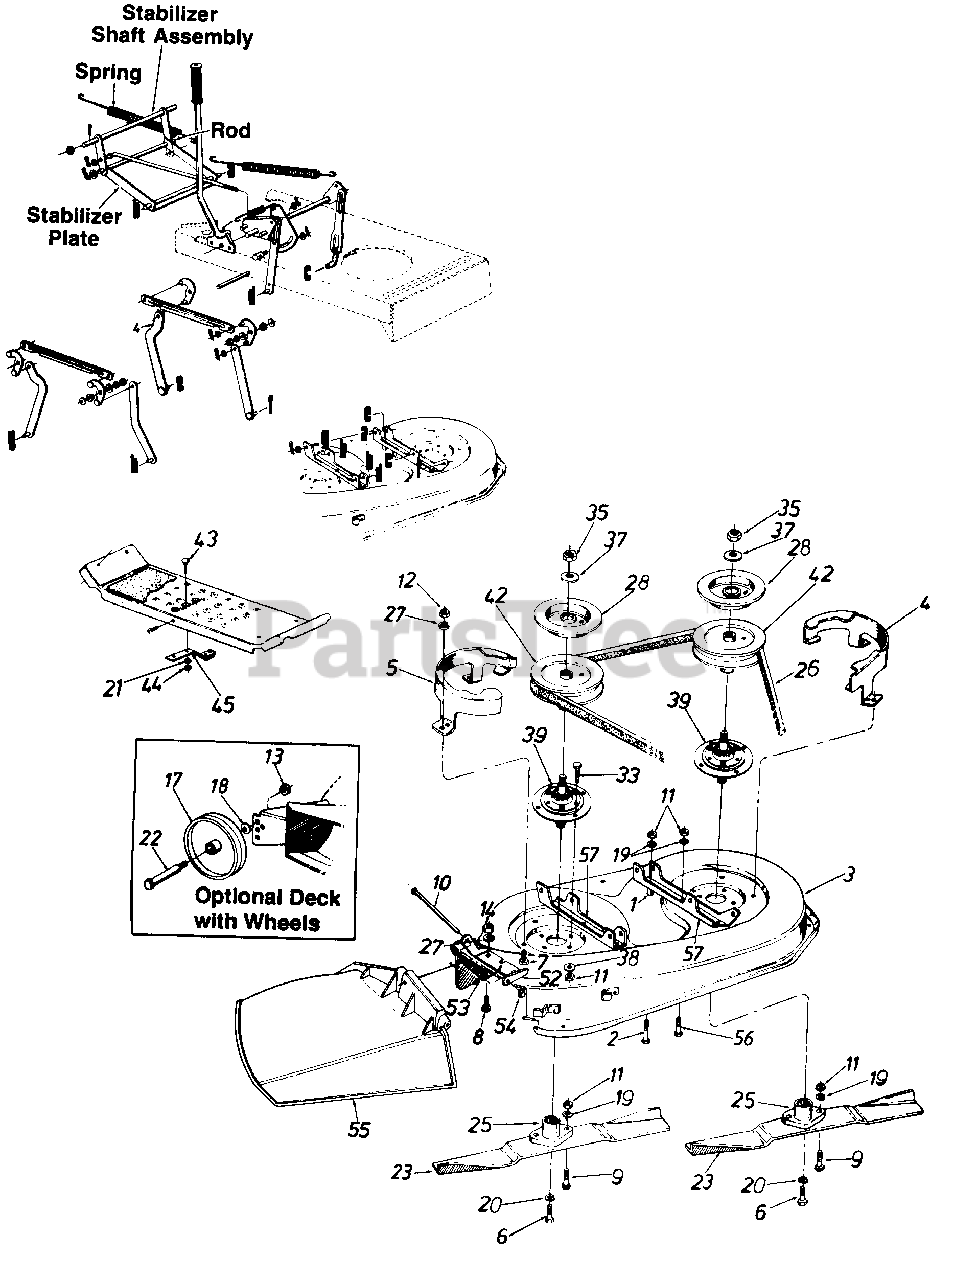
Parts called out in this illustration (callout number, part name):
1	Spacer.33" I.D. x .88"
2	Hex Bolt 5/16-24 x 1.25" Lg.
3	38" Deck Ass'y. w/Deck Wheels
7	Hex Bolt 1/4-28 x .62" Lg.
8	Truss Mach. Scr. 1/4-20 x .75"
9	Hex Bolt Special 5/16-24 x 1.0"
10	Hinge Pin
11	Hex Nut 5/16-24 Thd.
12	Hex Nut 1/4-28 Thd.
13	Hex Top L-Nut 3/8-16 Thd.
14	Hex Nut 1/4-20 Thd.
17	Deck Wheel 5"
18	Bell-Wash. 40" I.D. x .88" O.D.
19	L-Wash. 5/16" I.D.
20	L-Wash. 3/8" I.D. H.D.
21	L-Wash. l/4" I.D.
22	Shld. Bolt .498" Dia. x 1.53"
23	High-Lift Blade
25	Blade Adapter
26	V-Belt
27	Bell-Wash. 1/4" I.D.
28	Brake Disc
33	Hex Bolt 5/16-24 x .75* Lg.
35	Hex Jam Nut 5/8-18 Thd.
37	L-Wash. 5/8" I.D.
38	L-Wash. 5/16" I.D.
39	Blade Spindle Ass'y. Comp.
42	5" Dia. Pulley
43	Carr. Bolt 1/4-20 x .62"
44	Hex Nut 1/4-20 Thd.
45	Blade Brake Ass'y.
52	Hinge Mtg. Brkt.
53	Torsion Spring
54	Push Nut
55	Chute Ass'y. Comp.
56	Hex Bolt 5/16-24 x .75" Lg.
